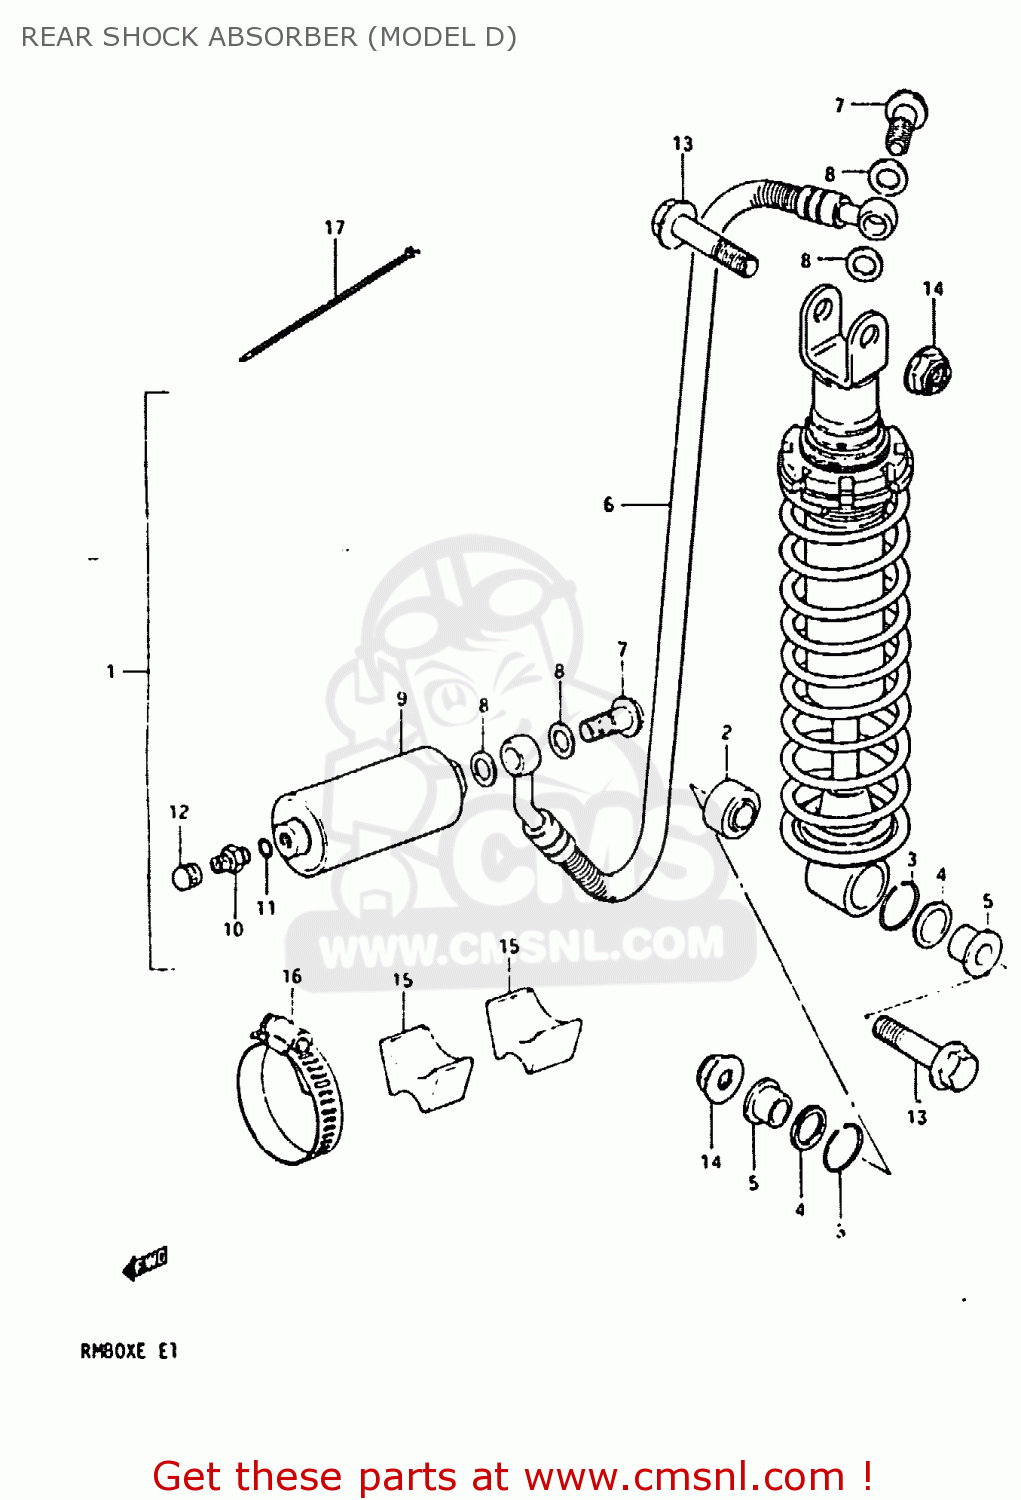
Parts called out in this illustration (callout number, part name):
1	ABSORBER ASSEMBLY,REAR SHOCK
2	BEARING
3	RING
4	DUST SEAL
5	SPACER
6	HOSE,REAR SHOCK ABSORBER
7	BOLT,REAR SHOCK ABSORBER
8	WASHER
9	RESERVE TANK,REAR SHOCK
10	VALVE,FRONT FORK AIR
11	O-RING (D:3.8 ID:19)
12	CAP,FRONT FORK AIR VALVE
13	BOLT(10X50)
14	NUT
15	CUSHION,REAR SHOCK ABSORBER
16	CLAMP
17	CLAMP
